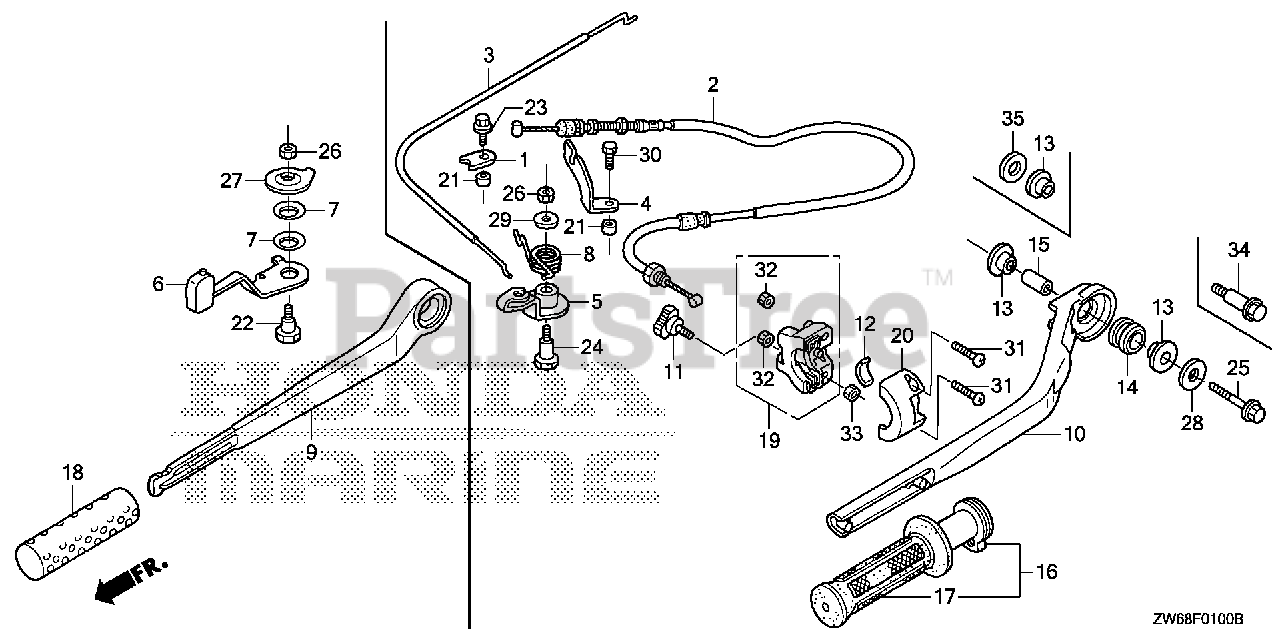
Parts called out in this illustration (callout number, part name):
1	HOLDER, CABLE
2	CABLE A, THROTTLE
3	CABLE B, THROTTLE
3	CABLE, THROTTLE (B)
4	HOLDER, CABLE
5	ARM, THROTTLE
8	SPRING, THROTTLE ARM
10	HANDLEBAR *NH246* (LOOSY GRAY)
11	BOLT, FRICTION
12	BLOCK, THROTTLE FRICTION
13	COLLAR, HANDLE MOUNTING
14	RUBBER, HANDLE MOUNTING
15	COLLAR, DISTANCE
16	GRIP, THROTTLE
17	GRIP, R. HANDLE
19	HOUSING, THROTTLE (LOWER)
20	HOUSING, THROTTLE (UPPER)
21	COLLAR, SEAT CATCH
21	COLLAR (6.2X8.5X5)
23	BOLT, FLANGE (6X12)
24	BOLT, HEX. (6X24)
25	BOLT, FLANGE (8X40)
26	NUT, HEX. (6MM)
28	WASHER (12.5X32)
29	WASHER, PLAIN (6MM)
30	BOLT, HEX. (6X14)
31	SCREW, PAN (5X20)
32	NUT, HEX. (5MM)
33	NUT, HEX. (6MM)
34	BOLT, SPECIAL (8X42)
35	WASHER, PLAIN (8MM)
